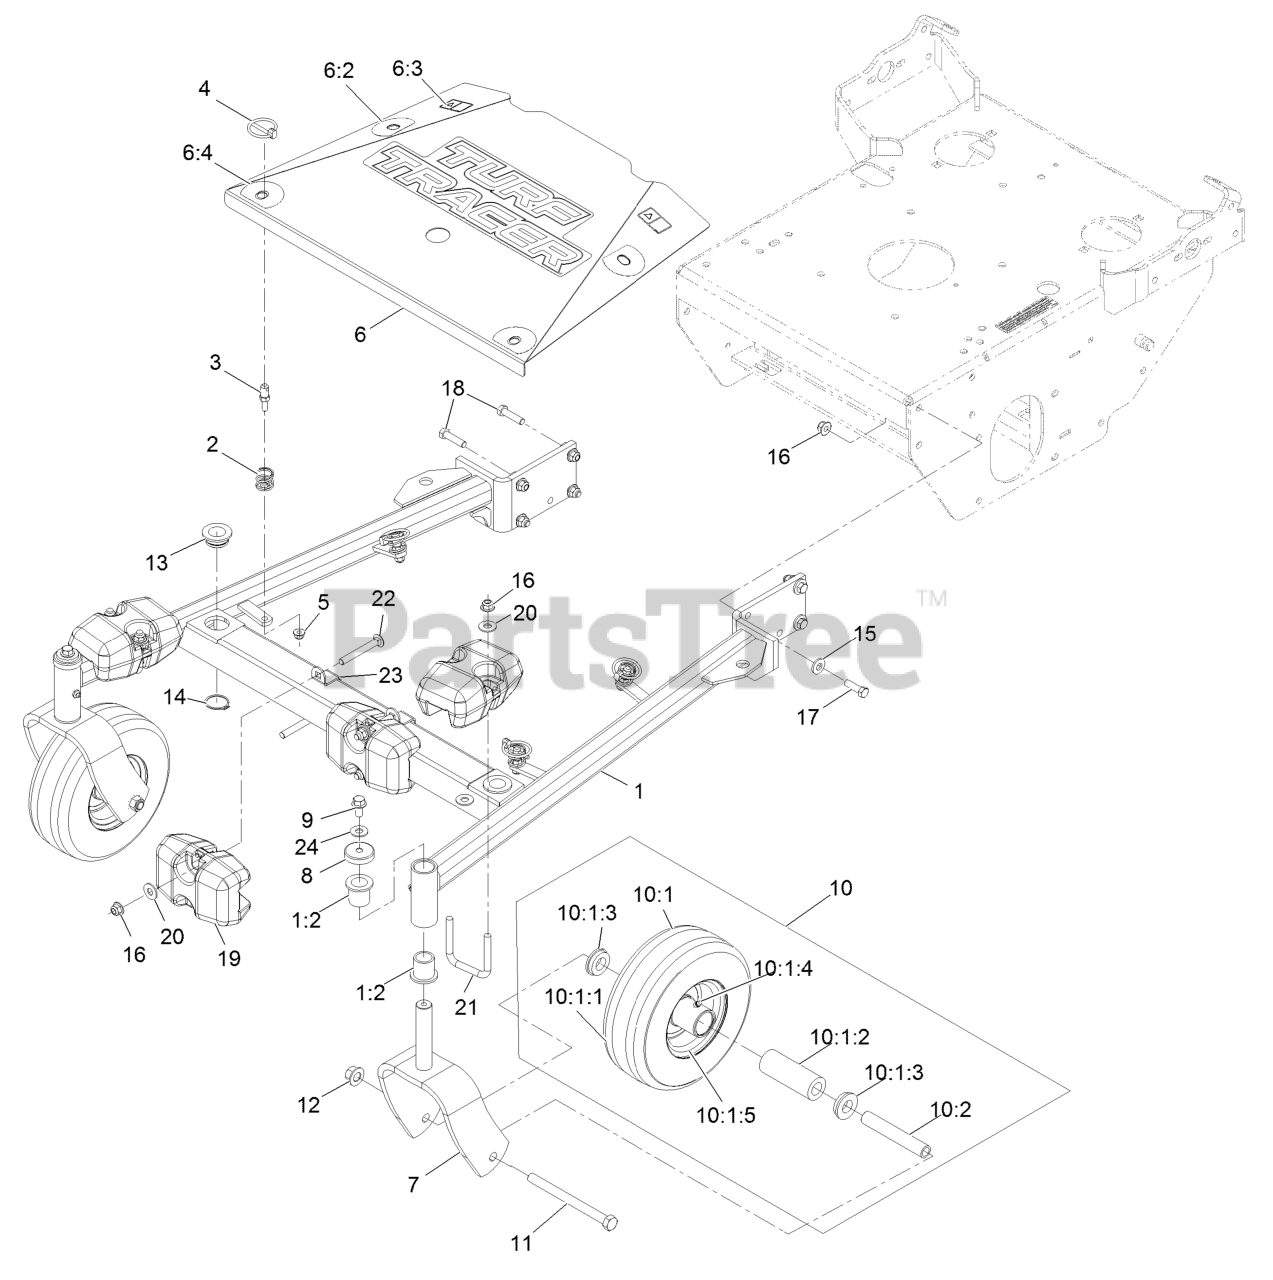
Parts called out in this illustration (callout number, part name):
1	ASM, FRAME W/ BUSHINGS, 4
1:2	BEARING-FLANGED
3	PIN-SPRING
4	PIN-LYNCH
5	NUT-HF, NI
6	ASM, SHIELD W/ DECALS, 48
6:2	DECAL-TURF TRACER
6:3	DECAL-WARNING
6:4	DECAL-SCRATCH COVER
7	FORK, CASTER
8	CAP, DUST
9	SCREW-HHF
10	KIT, SP CASTER WHEEL REPL
10:1	Wheel And Tire ASM
10:1:1	Tire
10:1:2	BEARING
10:1:3	BUSHING
10:1:4	FITTING-GREASE
10:1:5	Wheel
11	SCREW-HH
12	Nut-Lock 1/2-13
13	BUSHING-DECK
14	RING-RETAINING
15	WASHER-BELLEVILLE
16	NUT-HF, NI
17	SCREW-HH
18	SCREW-HH
19	WEIGHT-SUPPORT, CASTER
20	WASHER-FLAT
22	SCREW-CARR
23	STRAP, WEIGHT
